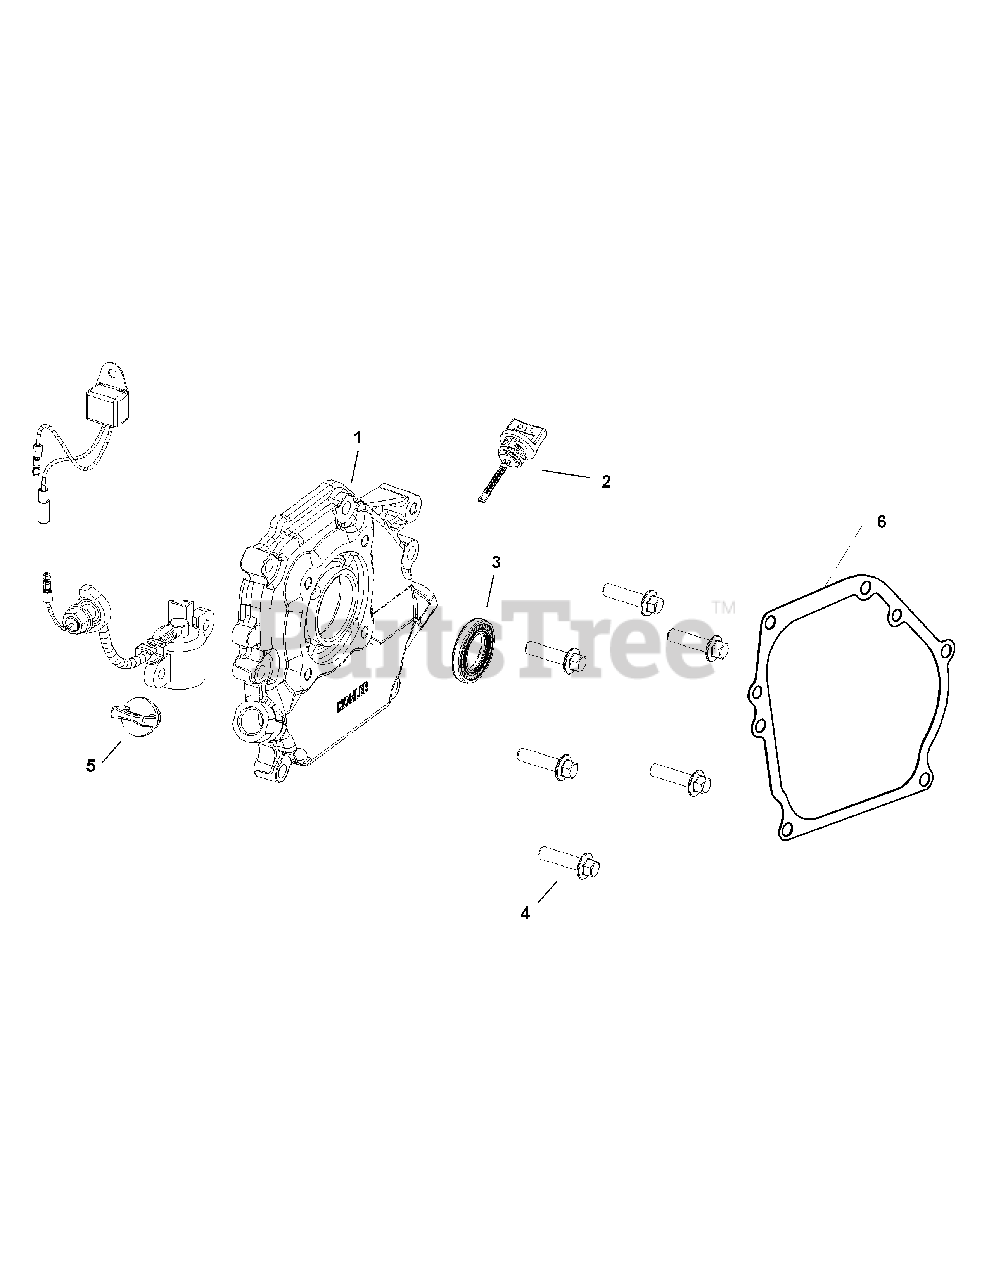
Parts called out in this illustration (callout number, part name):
1	Closure and Bearing Plate
2	Dipstick Assembly
3	Closure Plate Seal
4	Closure Plate Screw
5	Oil Fill Cap Assembly
6	Closure Plate Gasket
